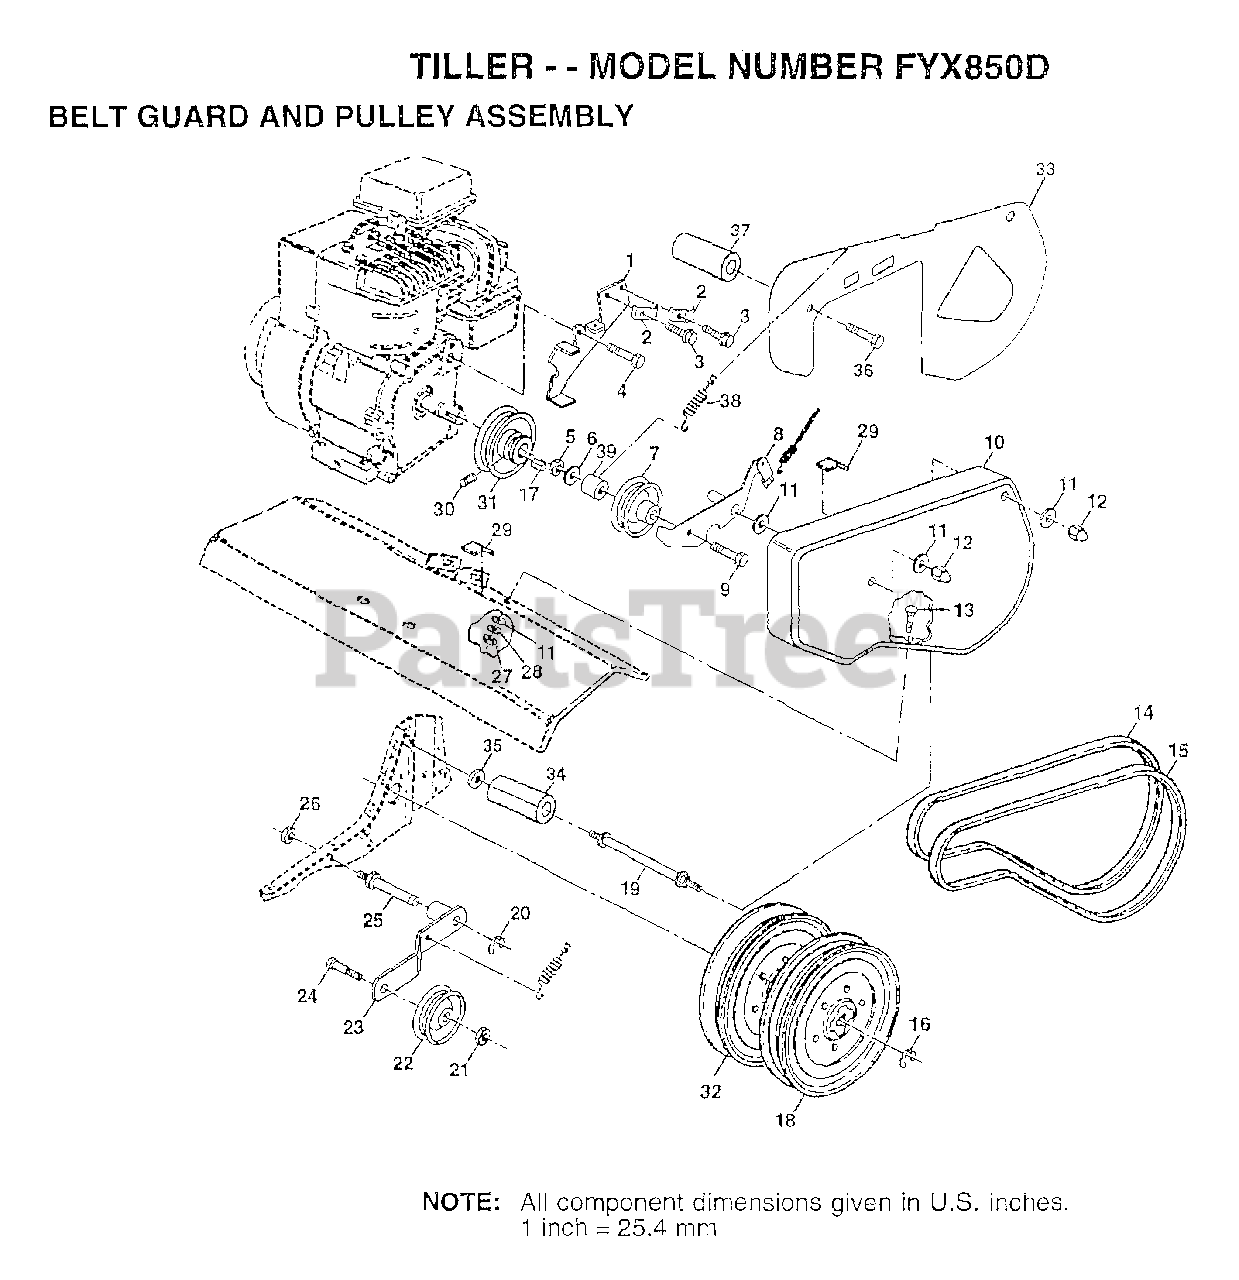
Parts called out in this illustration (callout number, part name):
1	ASM.BRKT.BELT.GRD
2	CONDIUT CLIP T
4	BOLT.HEX.HEAD
5	NUT.HEX.3/8-16UNC
6	WASHER
7	PULLEY W/SPACER
8	ASSY ARM REV.IDLR
11	WASHER
12	NUT-CAP TI
13	BOLT T
14	BELT-V
17	KEY T
18	SHEAVE.TRANS
19	BOLT TI
20	KLIP RING TI
21	NUT
22	"PULLEY,IDLER"
23	"ARM, IDLER"
25	SHAFT IDLER TI
26	JAM NUT TI
28	LOCKWASHER
29	PAD IDLER TI
30	SET SCREW
31	ENGINE PULLEY TI
32	"SHEAVE,TRANS.""D"""
33	"SHIELD,BELT GUARD"
34	SPACER.SPLIT
35	WASHER
36	BOLT.5/16X24X1
37	SPACER.SPLIT
38	"SPRING,EXT"
39	SPACER.500X384X23
